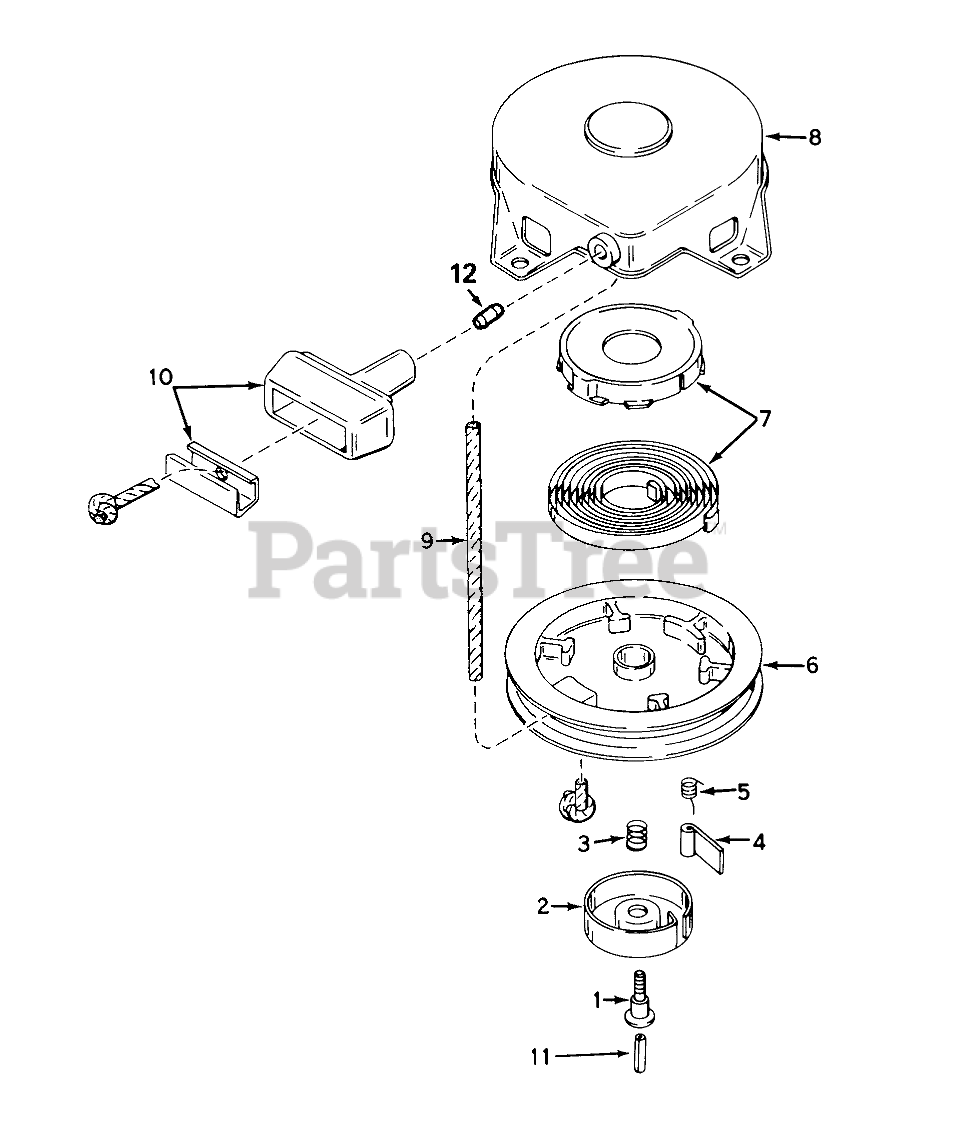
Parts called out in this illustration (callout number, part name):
2	Retainer
3	Spring-Brake
4	Dog-Starter
5	Spring-Dog
7	Spring & Keeper Assy
8	Housing Assy.-Starter (Incl. #1)
9	Rope-Starter (98 cut to length)
10	Assy., Starter
11	Centering
12	Retainer-Starter Rope
